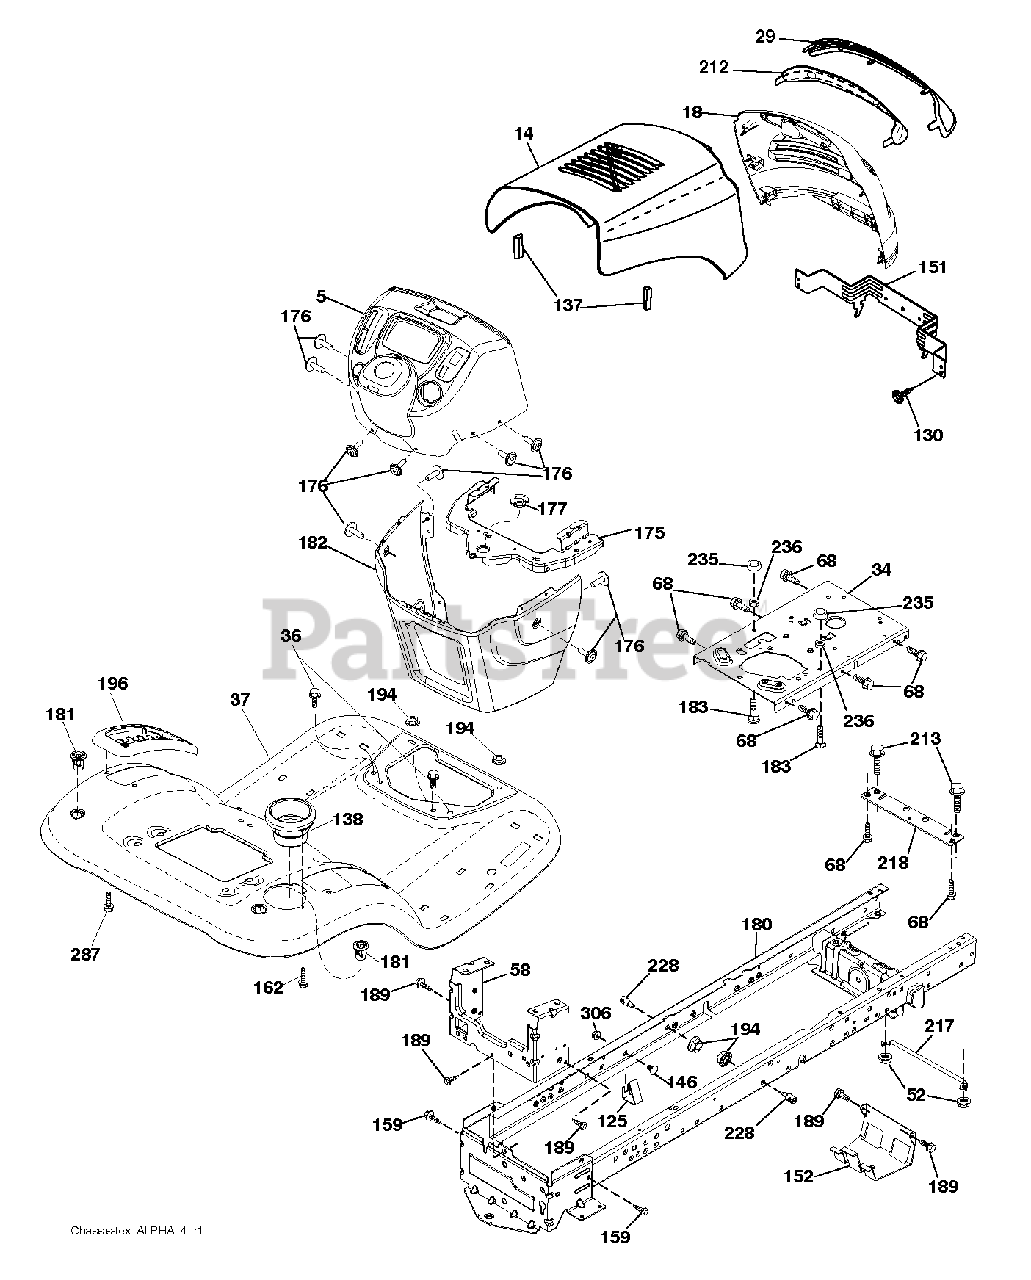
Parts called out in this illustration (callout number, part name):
5	DASH.P/L.TEX.CBL.CL.N/CHK.BLAC
14	HOOD.BLACK.ALPHA
18	GRILLE.ASM.ALPHA
29	LENS.ALPHA.BAR.LT
34	PLATE.ENGINE.WELDED.CHASSIS
36	SCREW 5/16"
37	FENDER.TLT.FS.W/CPH.428
52	LOCKNUT
58	DRAWBAR UPPER 2PC SMALL FENDER
68	SCREW LT
125	CLIP.FUEL.LINE
130	SCREW.#10 X 0.750.BOS (2 2)
137	BUMPER.HOOD.LARGE.1.75"
138	CUPHOLDER.TL.TEX.BLACK
146	BOLT.RDHD.SHT.SQNK.3/8-16X5/8
151	BRACKET.PIVOT.ALPHA.LT
152	SHIELD.BROWNING.W/TEX
159	SCREW, 3/8-16X3/4
162	SCREW.HI-LO.CONSOLE
175	CROSSMEMBER.LT
176	SCREW.#10-24X5/8.RN.QU
177	BUSHING STEERING
180	CHASS.WLDMNT.TL.12GA/2P.48/54
181	FEND/FTRST.PCH.CPH.NFW
182	DASH.LOWER.LT.CCS
183	BOLT.5/16-18X1-1/4 FULL THD
189	SCREW
194	NUT LOCK HEX FLANGE 5/16-18
196	CONSOLE.ASM.DECKLFT.BL/RBT.TLT
212	INSERT.ALPHA.REFLECTIVE.LT.
213	BOLT
217	ROD.PIVOT.HOOD
218	X-PIECE.HOOD.STOP.NON/
228	STUD.FASTNER.W/ANTI-ROTATE
235	SPACER FENDER
236	NUT.CENTERLOCK.5/16-
287	SCREW 1/4X20
306	NUT LOCK FLG 3/8-16 UNC
